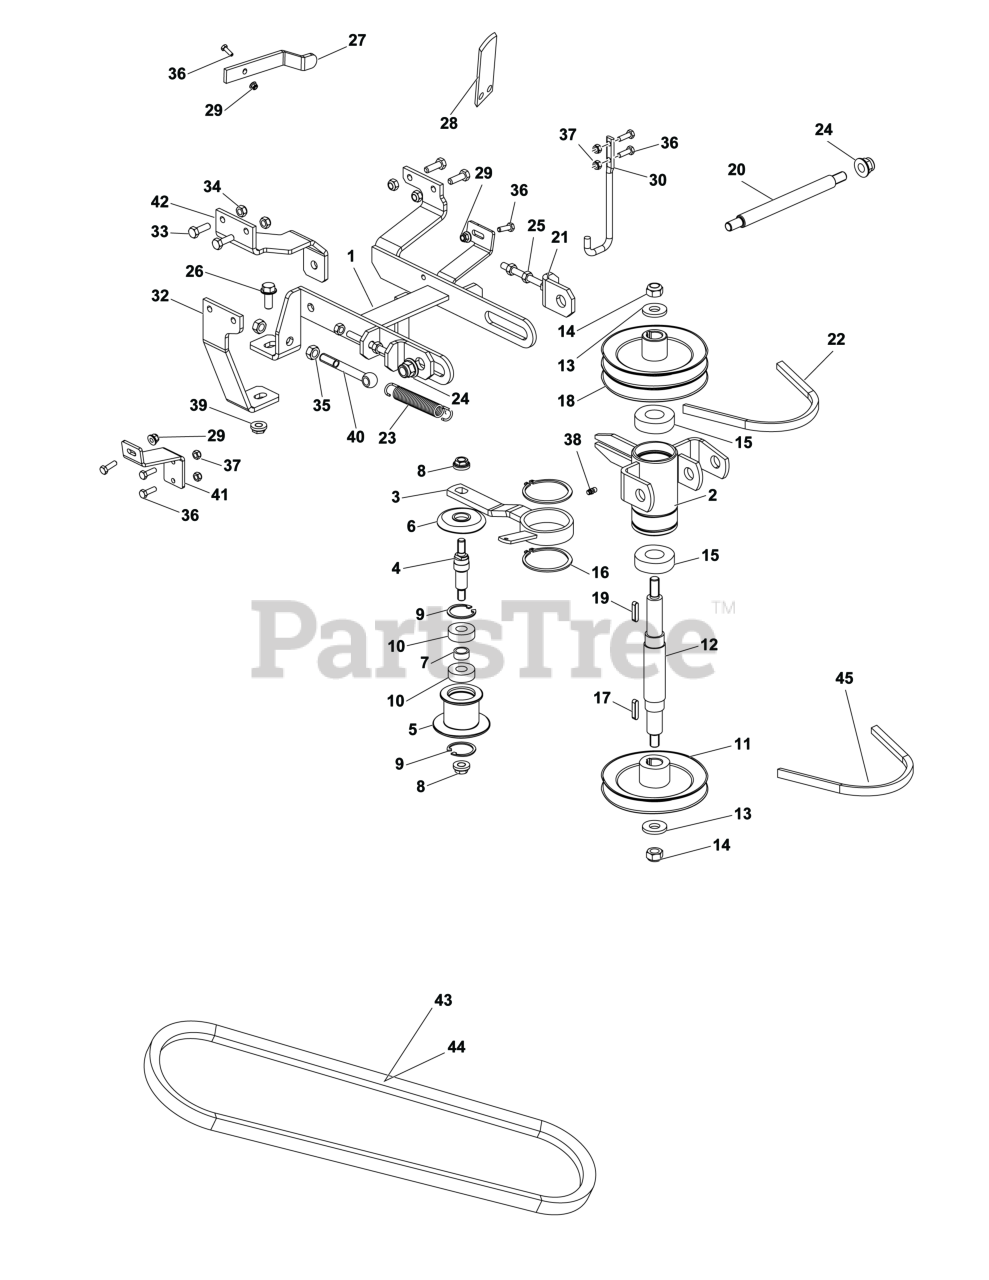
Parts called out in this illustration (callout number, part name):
1	CARRIER
21	STRAINER
22	BELT
38	ZERK, Grease Fitting
40	EYE BOLT
43	BELT
44	BELT
45	BELT
